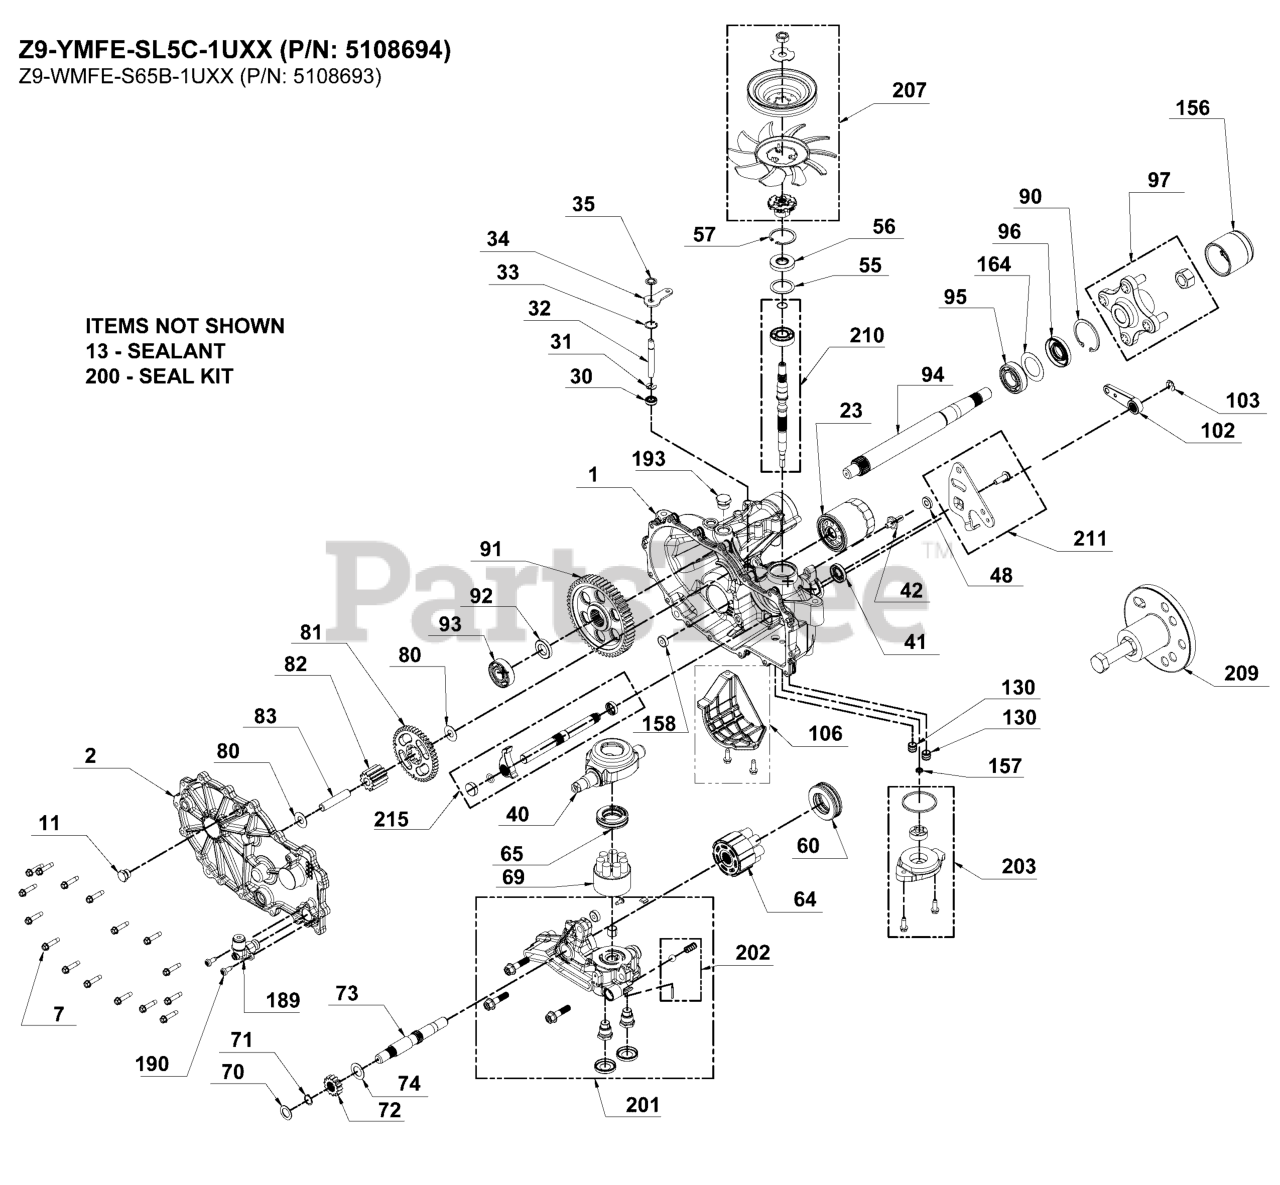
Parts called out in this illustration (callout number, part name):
1	KIT, MAIN HOUSING LH, CHARGE, CONTROL
2	KIT, COVER, SIDE, LH, COOLER
7	SCREW, HEX WASHER
13	TUBE, SEALANT
34	ARM, BYPASS
35	RING, RETAINING .375 EXTERNAL
40	SWASHPLATE, TRUNNION
48	SPACER
55	SPACER (50951)
56	Lip Seal 17 x 40 x 7 PTC
57	Spacer
64	KIT, 16cc CYLINDER BLOCK ASSEMBLY STEAM TREAT
65	BEARING, THRUST PLASTIC CAGE
69	KIT, BLOCK 7 PISTON
70	WASHER, .63 X 1.00 X .05 FLAT
71	RING-SNAP (44145)
72	GEAR, 14T (STEEL)
73	SHAFT, MOTOR
74	WASHER, .71 X 1.16 X .04 FLAT
80	WASHER, .51 X 1.00 X .03 FLAT
82	GEAR, 11T (STEEL)
83	PIN, JACKSHAFT
90	RING, RETAINING 2.25 INTERNAL
91	GEAR, 54T FORGED
93	KIT, BEARING
94	SHAFT, AXLE, ZT-3400, 53528
95	BEARING, BALL, AXLE INBOARD
96	KIT, SEAL, AXLE - HG# 53699
97	HUB, ASM, TRANS 5101188/89 & 5102154/55
102	BRAKE ARM, ZT3400
103	E-CLIP, BRAKE ARM, ZT3100 & ZT3400
106	KIT, FILTER GUARD
130	TUBE, CHARGE TRIPLE O-RING
156	CAP, AXLE, ZT-3400, 53501
157	KIT, GEROTOR SEAL
158	MAGNET
164	WASHER, 1.355 x 2.035 x .021 FLAT
189	ASSEMBLY, AUX COOLER PORT (#55672)
200	KIT, SEAL - HG# 73239
201	KIT, CENTER SECTION, LH CHARGE
202	KIT, CHARGE RELIEF
203	KIT, CHARGE PUMP, ZT2800, ZT3100
207	FAN & PULLEY KIT, ZT3400'S, STAND-ON
209	KIT, HUB PULLER
210	KIT, INPUT SHAFT
211	KIT, CONTROL ARM
215	KIT, OUTBOARD, RH ROT B / LH ROT A
5108693	TRANSAXLE, ZT3400, Z9-WMFE-SL5B-1UXX
5108694	TRANSAXLE, ZT3400, Z9-YMFE-SL5C-1UXX
